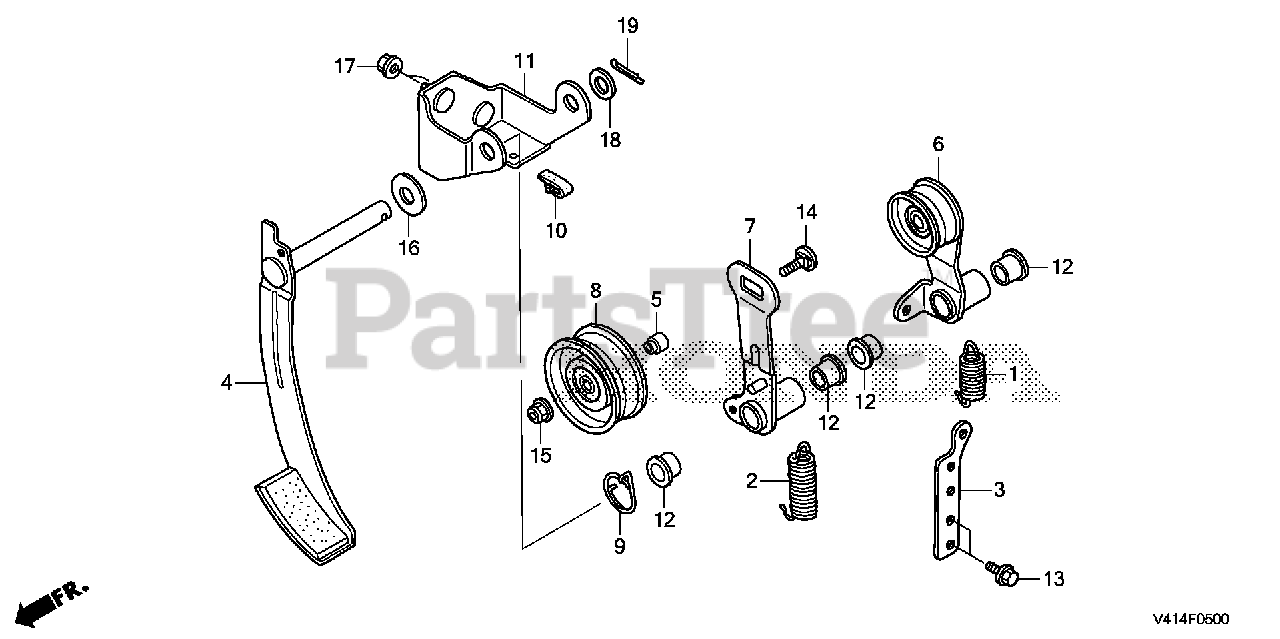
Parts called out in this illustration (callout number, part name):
1	SPRING, WHEEL TENSION RETURN
2	SPRING, AUGER TENSIONER RETURN
3	STAY, TENSIONER SPRING
4	ARM, AUGER BRAKE
5	COLLAR, ROLLER
6	ARM, WHEEL TENSIONER
7	ARM, AUGER TENSIONER
9	SPRING, BRAKE ARM
10	RUBBER, STOPPER
11	BRACKET, TENSION ARM
12	BUSH, CHANGE ARM
13	BOLT, FLANGE (6X12) (CT200)
14	BOLT, ROLLER
15	NUT, SELF-LOCK (8MM) (CLINCH)
16	WASHER, BRAKE ARM
17	NUT, FLANGE (8MM)
18	WASHER, PLAIN (12MM)
19	PIN, SPLIT (3.0X18)
